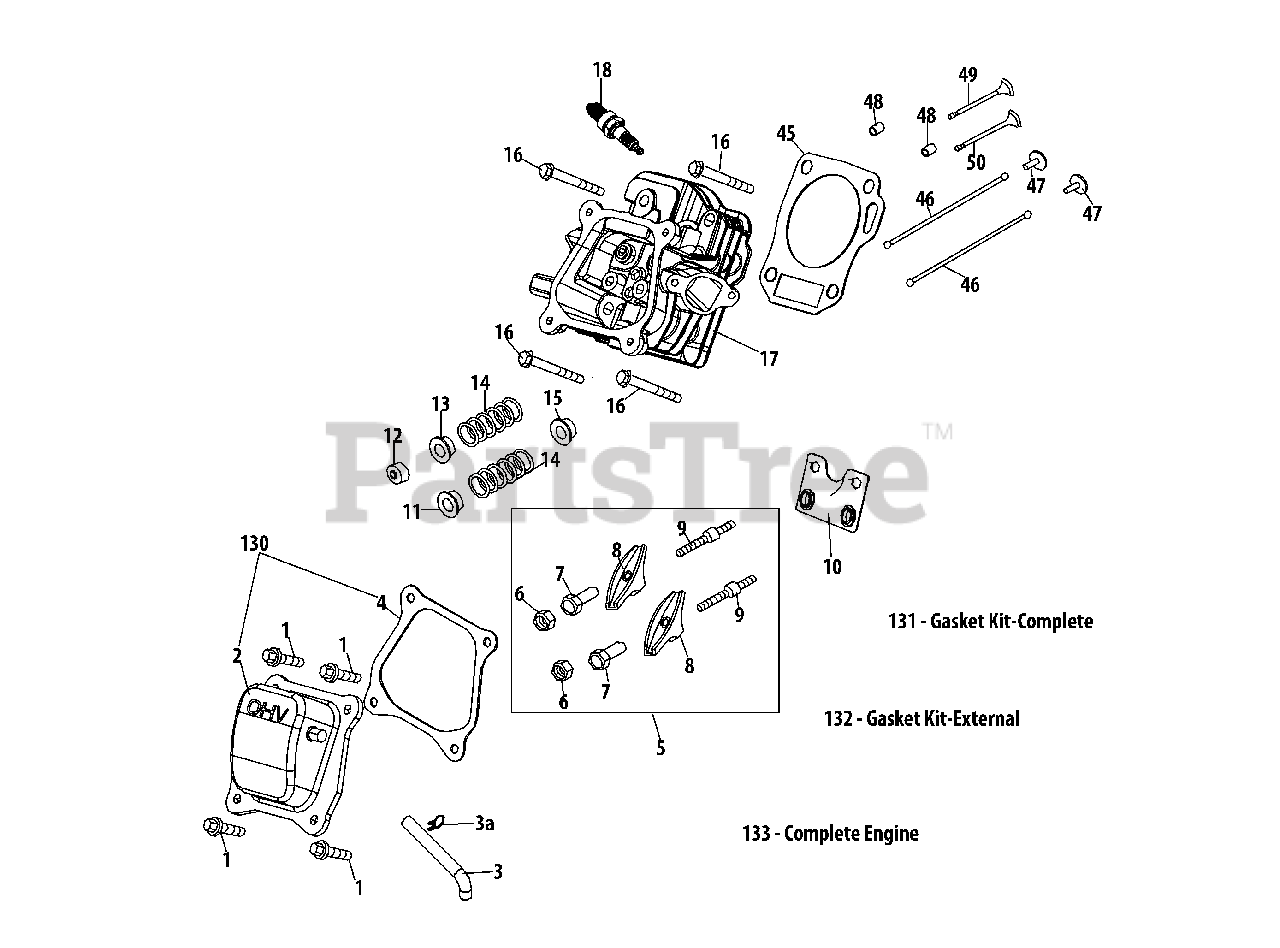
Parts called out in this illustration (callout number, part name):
1	Bolt M6×16
2	Valve Cover
3	Breather Hose
4	Valve Cover Gasket
5	Rocker Arm Assembly
6	Nut,Pivot Locking
7	Adjusting Nut ,Valve
8	Rocker Arm
9	Bolt,Pivot
10	Push Rod Guide
11	Valve Spring Retainer (Intake)
12	Adjuster, Exhaust Valve
13	Valve Spring Retainer (Exhaust)
14	Valve Spring
15	Valve Seal (Intake)
16	Bolt M8×55
17	Cylinder Head Asm
18	Spark Plug/F6Rtc
45	Gasket,Cylinder Head
46	Push Rod Kit
47	Tappet
48	Dowel Pin 10×16
49	Valve Kit
50	Valve Kit
130	Valve Cover Kit
131	Gasket Kit-Complete
132	Gasket Kit-External
133	Complete Engine
